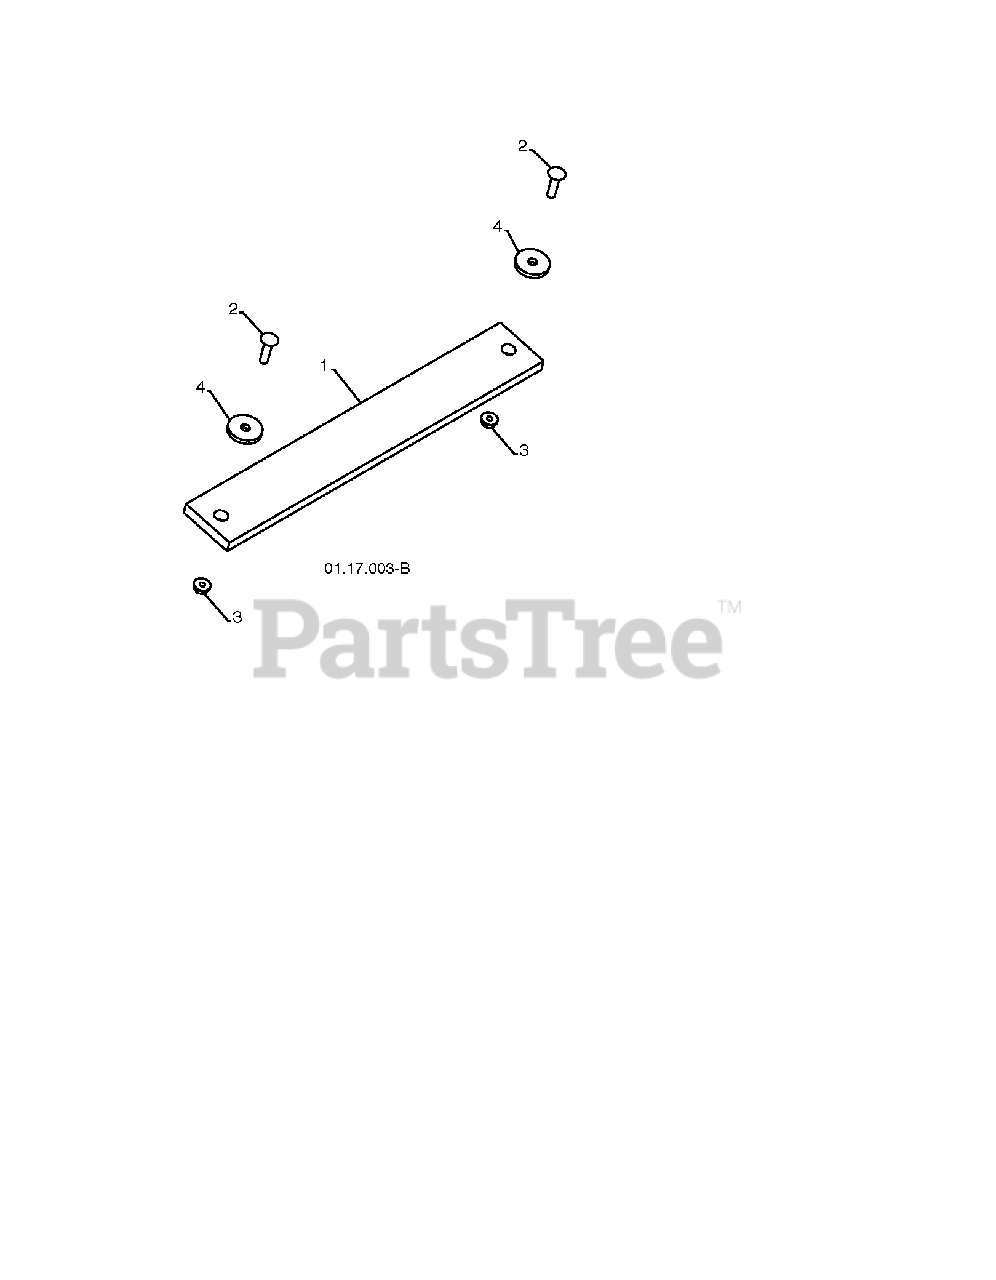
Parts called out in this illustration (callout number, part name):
1	WEIGHT AUGER HOUSING 30
2	BOLT.CARRIAGE.5/16-18
3	NUT, LOCK 5/16-18
4	WASHER.FLAT.34X1.38X22
